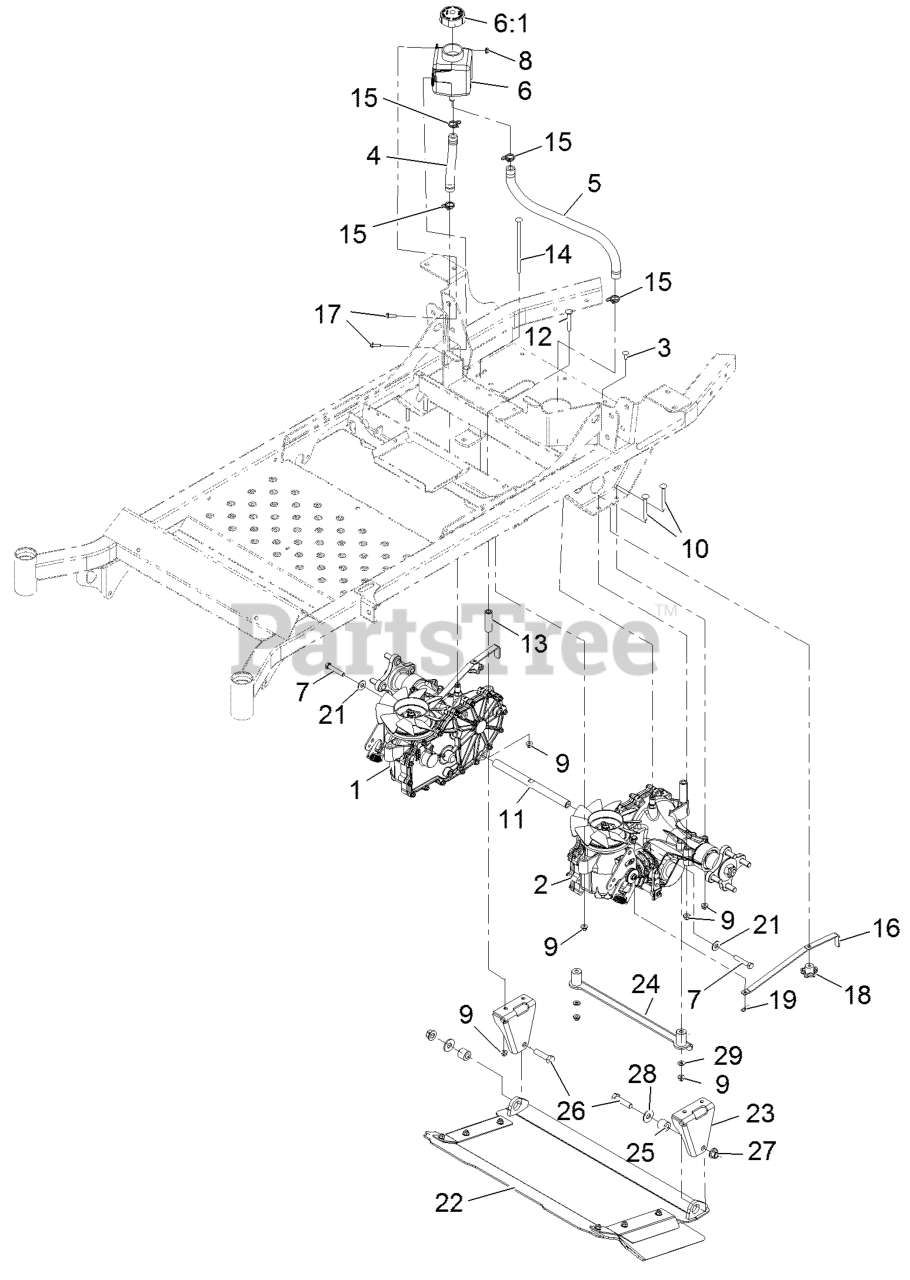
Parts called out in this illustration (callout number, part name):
1	TRANSAXLE ASM
2	TRANSAXLE ASM
3	BOLT-CARR
4	HOSE-HYDRAULIC
5	HOSE-HYDRAULIC
6	TANK-HYD
6:1	CAP-RESERVOIR, HYD
7	SCREW-HH W/LOCTITE
9	NUT-HF, NI
10	SCREW-CARR
11	SHAFT-SPACER
12	BOLT-CARR
13	SPACER-HYDRO
14	SCREW-CARR
15	CLAMP-HOSE
16	ARM-BYPASS, HYDRO
17	SCREW-HWH
18	KNOB-HANDLE
19	PIN-COTTER
21	WASHER-FLAT
22	DISCHARGE TUNNEL ASM
23	BRACKET-MOUNT, DISCHARGE
24	ASM-HYDRO GUSSET
25	BUSHING-SLEEVE
26	SCREW-HH
27	Nut-Lock 1/2-13
28	WASHER-FLAT
29	WASHER-SPRING
